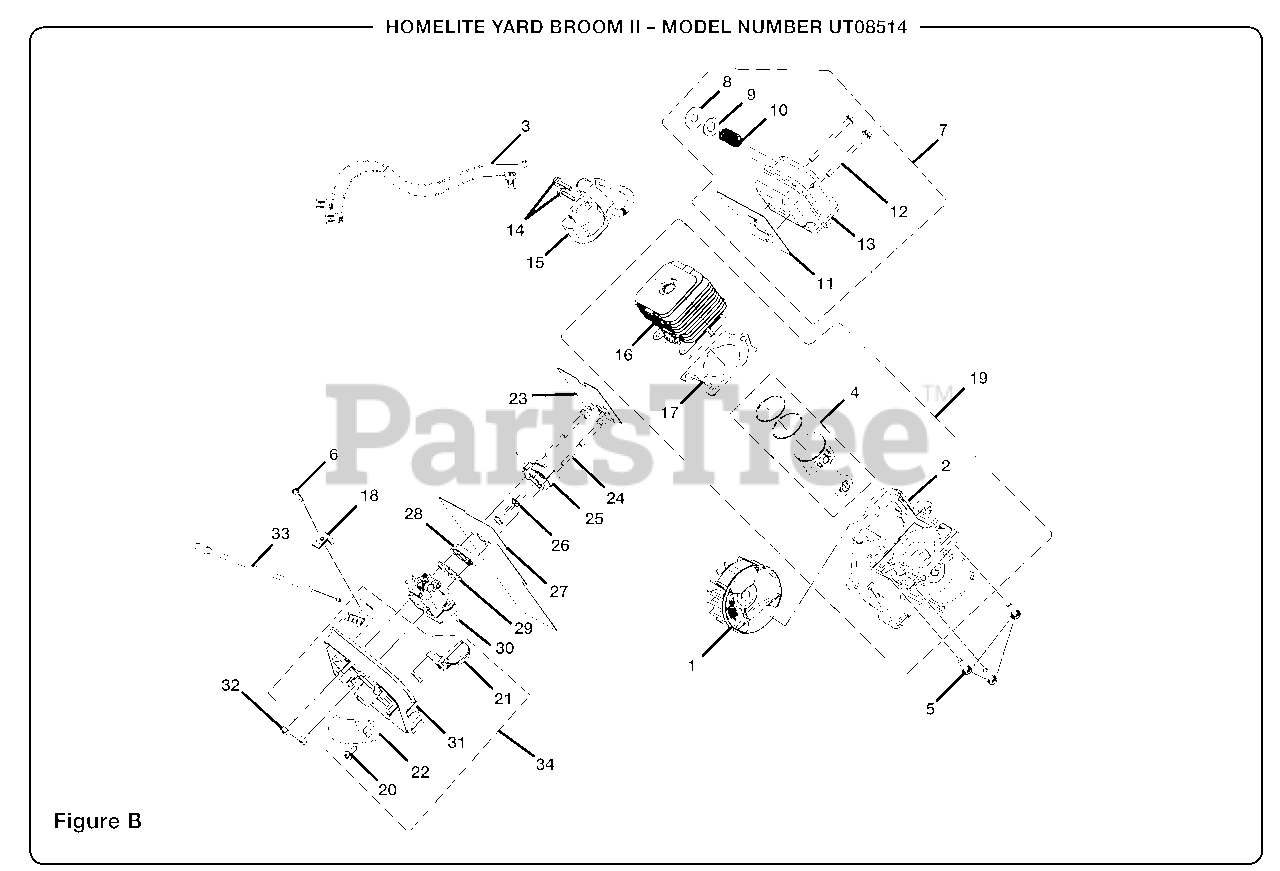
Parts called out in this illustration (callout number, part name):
1	Fly Wheel Assembly
2	Crankcase Assembly
3	Ignition & Switch Harness
4	Piston & Rod Assembly
5	Screw (M5 X 20 mm)
6	Screw (M4 X 1.75 X 16 mm)
7	Muffler Assembly
8	Insulating Washer
9	Flat Washer
10	Compression Spring
11	Muffler Gasket
12	Screw (10-24 Hex Hd.)
14	Screw (8-32 X1.0 in.)
15	Ignition Module
16	Cylinder
17	Cylinder Gasket
18	Throttle Cable Clip
19	Short Block Assembly
20	Screw (M4)
21	Choke Lever
22	Choke Plate
23	Heat Dam Gasket
24	Carburetor Mounting Bolt
25	Heat Dam
26	Screw (10-24 X 1.11 Pan Hd.)
27	Carburetor Gasket
28	Spacer
29	Gasket
30	Carburetor (Walbro WYC-10)
31	Air Filter Box
32	Hex Nut (10-24)
33	Throttle Cable
34	Air Box Base Assembly
